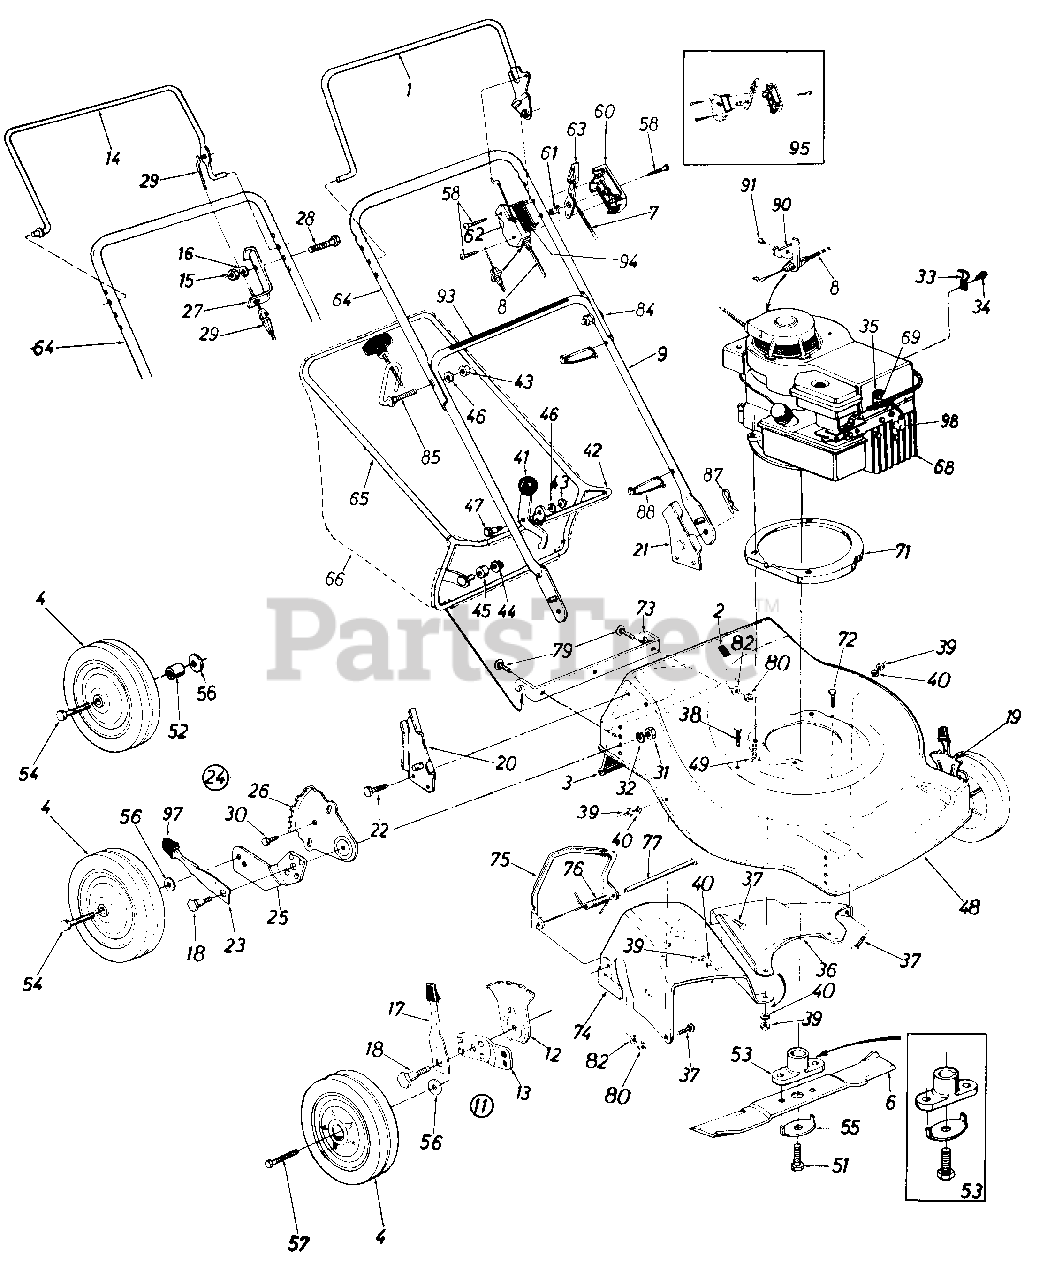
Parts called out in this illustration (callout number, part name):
1	Control Handle Ass'y.
3	Rear Flap Ass'y.
4	7" Wheel Ass'y. Comp.
6	20" Blade
7	Throttle Wire-58"
8	Control Cable-43"
9	Lower Handle (Painted)
11	Front Height Adj. Ass y.-R.H.
12	Front Index Plate
14	Control Handle
15	Hex Nut 1/4-28 Thd.
16	Spr. Wash. .265" I.D. x .562"
17	Spring Lever w/Knob
18	Shld. Bolt .50" Dia. x .375
19	Front Height Adj. Ass y.-L H.
20	Handle Brkt. Ass'y.-R.H.
21	Handle Brkt. Ass'y.-L.H.
22	Hex Wash. Hd. AB-Tap Scr. 1/4 x .62" Lg.
23	Spring Lever
24	Rear Height Adj. Ass'y.-R.H.
25	Rear Pivot Bar-R.H.
26	Rear Index Plate
27	Cable Mounting Bracket
28	Hex Bolt 1/4-28 x 1.75" Lg.
29	Control Cable-55"
30	Hex Wash. Hd. Tap Scr. 1/4 x .62" Lg.
31	Hex Nut 3/8-16 Thd.
32	Bell-Wash. 3/8" I.D.
33	Cable Clip
34	Hex AB-Tap Scr. #10 x .38"
35	Casing Clamp
36	Rear Chute Baffle-L.H.
37	Carr. Bolt 1/4-20 x .50" Lg.
38	Hex Bolt 1/4-20 x .88" Lg.
39	Hex Nut 1/4-20 Thd.
40	L-Wash. 1/4" I.D.
41	Cam Lever Grip Ass'y.
42	Grass Catcher Lower Frame
43	Hex Nut 5/16-18 Thd.
44	Push Cap 3/8" Rod
45	Plastic Roller
46	L-Wash. 5/16" I.D.
47	Shld. Bolt .437" Dia. x .180"
51	Hex Bolt 3/8-24 x 1.5" Lg. (Grade 5)
52	Spacer
53	Blade Adapter Kit
54	Rear Axle Bolt
55	Blade Bell-Wash.
56	Bell-Wash. .400" I.D. x .88"
57	Front Axle Bolt
58	Truss Mach. Hi-B Tap Scr. #12 x 1.5" Lg.
60	Control Panel Half
61	Control Disc Pin
62	Clutch Panel Half
63	Throttle Control Lever
64	Upper Handle (Painted)
65	Grass Catcher Upper Frame
66	Grass Bag (With Flip Top)
68	Engine
69	Hex AB-Tap Scr. #8 x .38"
71	Engine Mounting Cover
72	Hex Self-Tap Scr. 1/4-20 x .75"
73	Grass Catcher Hitch Brkt.
74	Rear Chute Baffle-R.H.
75	Chute Door
76	Torsion Spring
77	Hinge Pin
79	Carr. Bolt 1/4-20 x .75" Lg.
80	Hex Sems Nut 1/4-20 Thd.
82	Fl-Wash. .281" I.D. x 1.25"
84	Curved Carr. Bolt 5/16-18 x 1.38" Lg.
85	Rope Guide Bolt
87	Hairpin Cotter
88	Cable Tie
90	Cable Brkt.
91	Pop Rivet
93	Instruction Label-Handle
94	Control Label-Throttle
95	Kit-Control Housing Comp.
97	Spring Lever Knob
98	Spark Plug Boot
